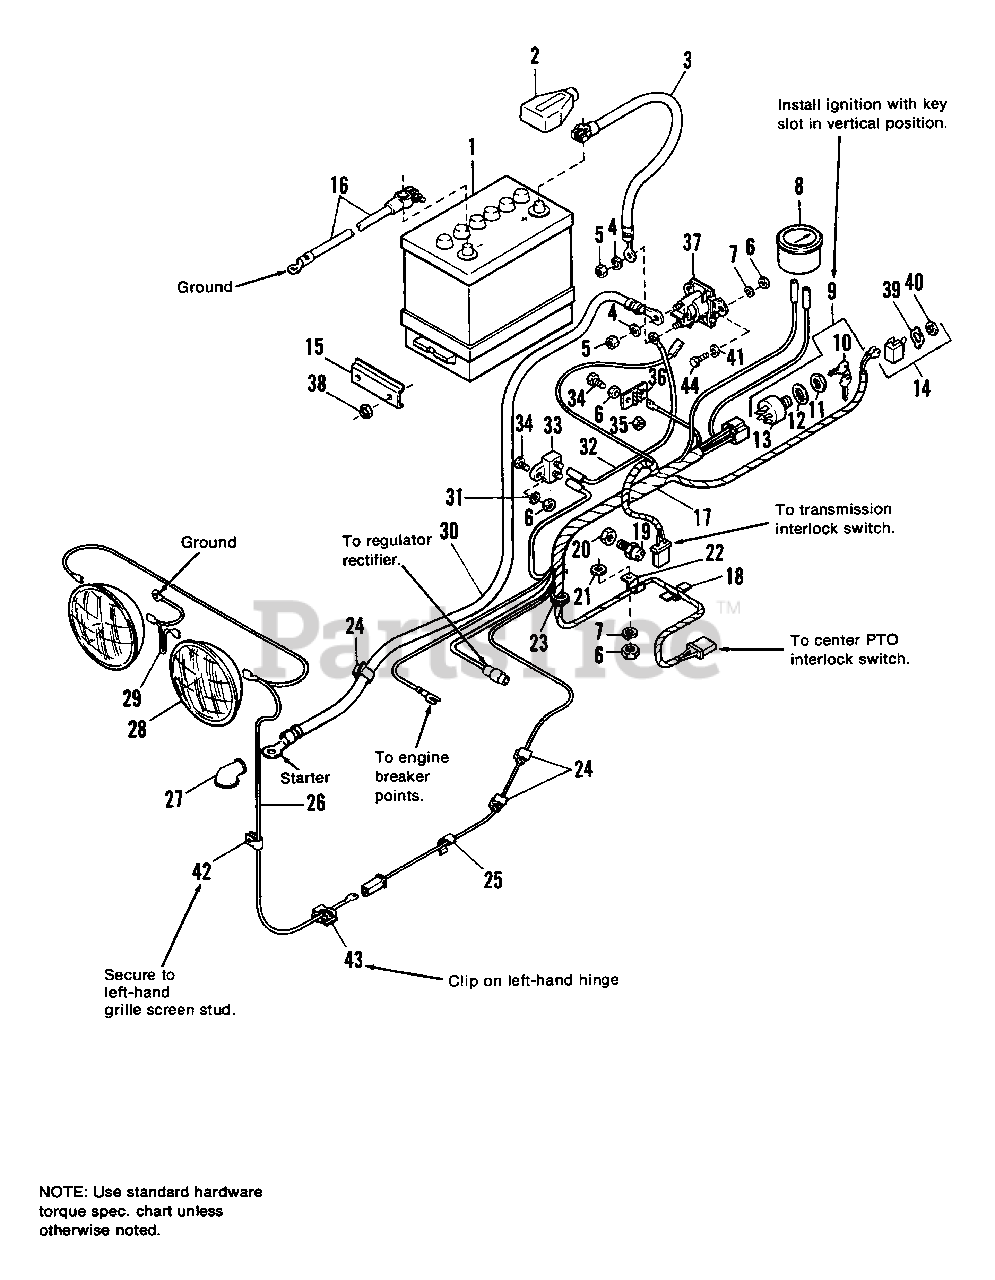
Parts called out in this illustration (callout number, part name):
1	BATTERY (Includes decal)
2	Insulating Cable Boot
3	CABLE (Battery to Solenoid)
4	LOCKWASHER, 5/16
5	NUT, Hex, Full, 5/16-18
6	NUT, Hex, Full, 1/4-20
7	LOCKWASHER, 1/4
10	KEY SET (2)
11	NUT, Special
12	LOCKWASHER, Int., 5/8
14	SWITCH, Toggle
16	CABLE (Battery to Ground)
17	HARNESS ASSY.
18	CLIP, Wire
19	SWITCH, Interlock
20	NUT, Pal
21	WASHER, Plain
22	CLIP, Cable
24	CLIP, Tinnerman
25	CLIP, Tinnerman
27	COVER, Terminal
28	LAMP, Sealed Beam, G.E. #4411-1
29	WIRE ASSY.
30	CABLE (Solenoid to Starter)
31	LOCKWASHER, Ext., 1/4
33	BREAKER, Circuit
34	CAPSCREW, Hex Hd., 1/4-20 x 5/8
35	LOCKNUT, Hex, 1/4-20
36	BOARD, Terminal
37	SOLENOID, Starter
38	LOCKNUT, Hex, Esna, 5/16-18
40	NUT, Switch
41	WASHER, Special
42	CLAMP, Wire
43	CLIP, Speed Cable
44	CAPSCREW, Hex Hd., 1/4-20 x 3/4
